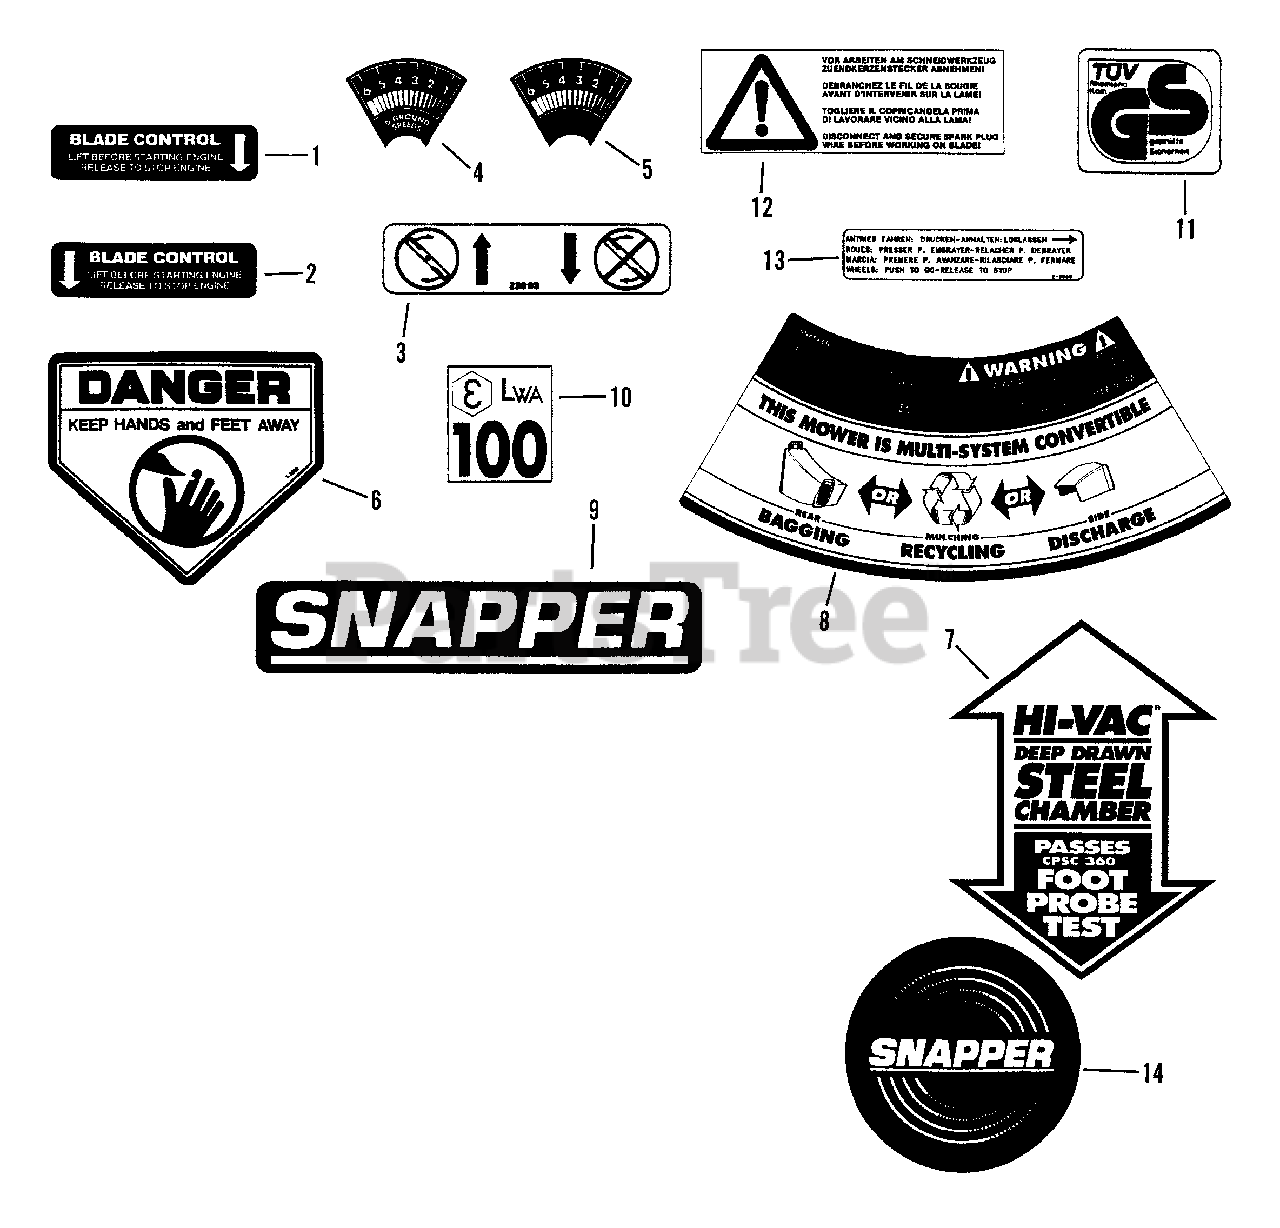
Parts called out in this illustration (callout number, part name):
1	DECAL, Blade Control
2	DECAL, Blade Control
3	DECAL, Blade Control (European Models Only)
4	DECAL, Speed Sector
5	DECAL, Speed Sector (European Models Only)
6	DECAL, Danger
7	DECAL, Hi-Vac/Foot Probe
8	DECAL, Convertible
9	LOGO, Molded
10	DECAL, Noise Control (European Models Only)
11	DECAL, GS (European Models Only)
12	DECAL, Spark Plug (European Models Only)
13	DECAL, Wheel Control (European Models Only)
14	DECAL, Snapper
